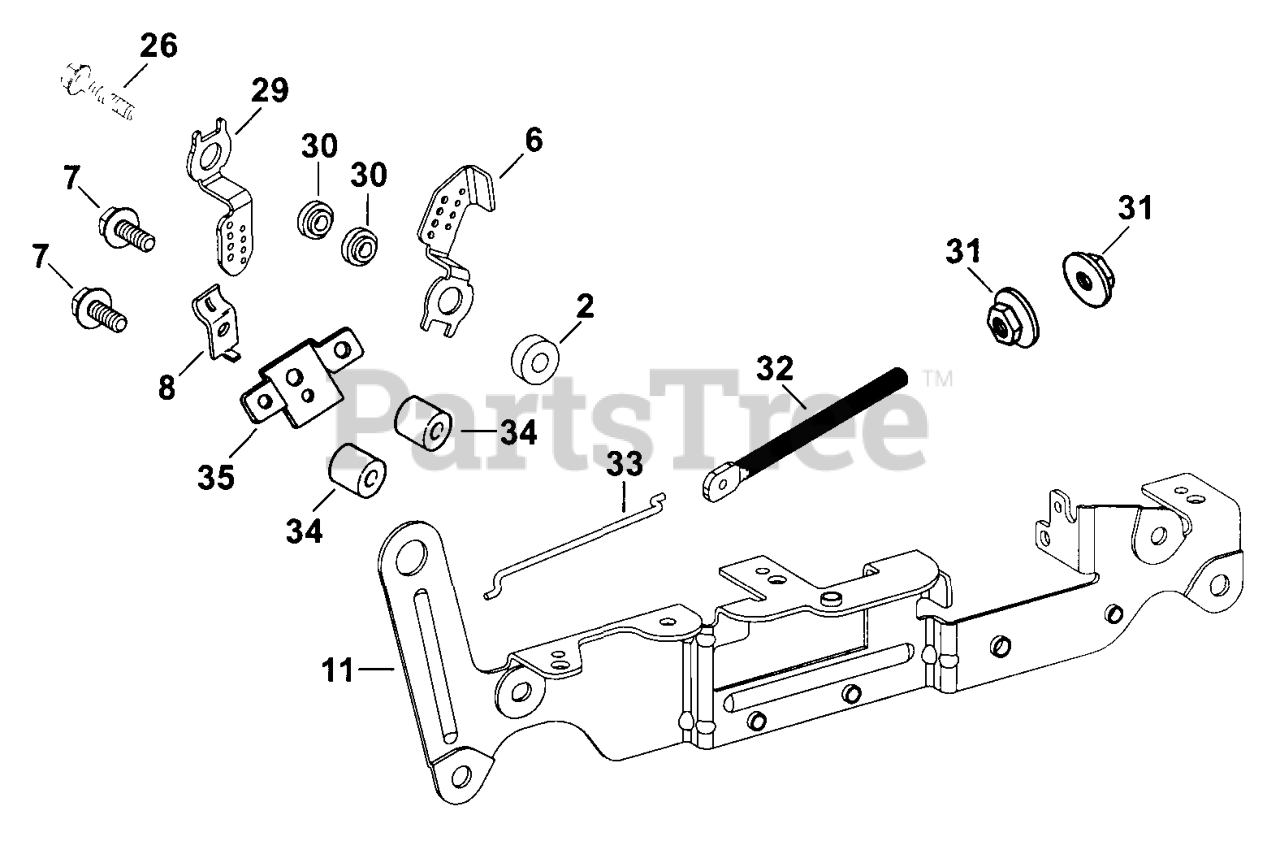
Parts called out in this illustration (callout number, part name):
6	LEVER, THROTTLE - DISCONTINUED
7	SCREW, FLG THD FRM M5X.8X20-(#25086399S)
8	CLAMP, CABLE
11	BRACKET, CONTROL - (#DSC)
26	SCREW, FLNGTHDFRM M6X1.0X30-(#25086401S)
29	LEVER, THROTTLE-DISCONTINUED
35	BRACKET, BOWDEN CLAMP
